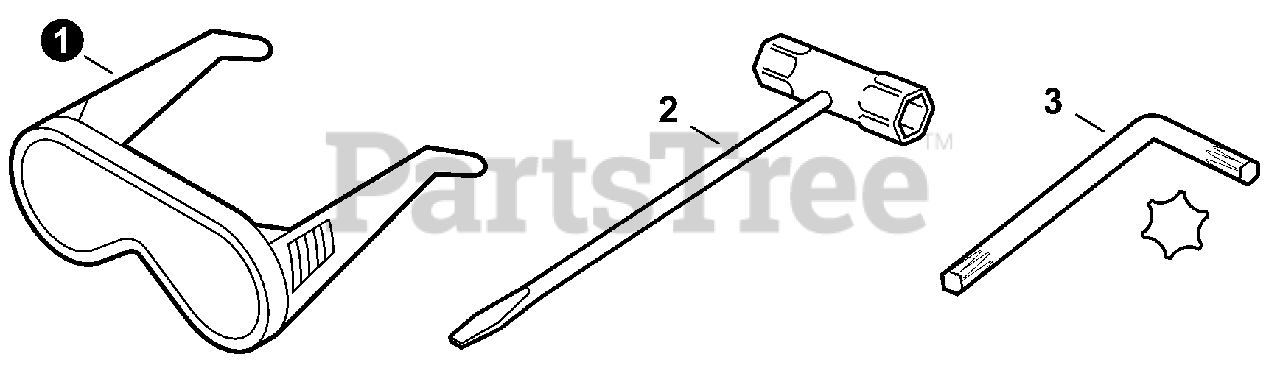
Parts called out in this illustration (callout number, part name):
1	T-WRENCH 10×19mm
2	WRENCH, ALLEN T27 80×30
3	GLASSES, SAFETY
